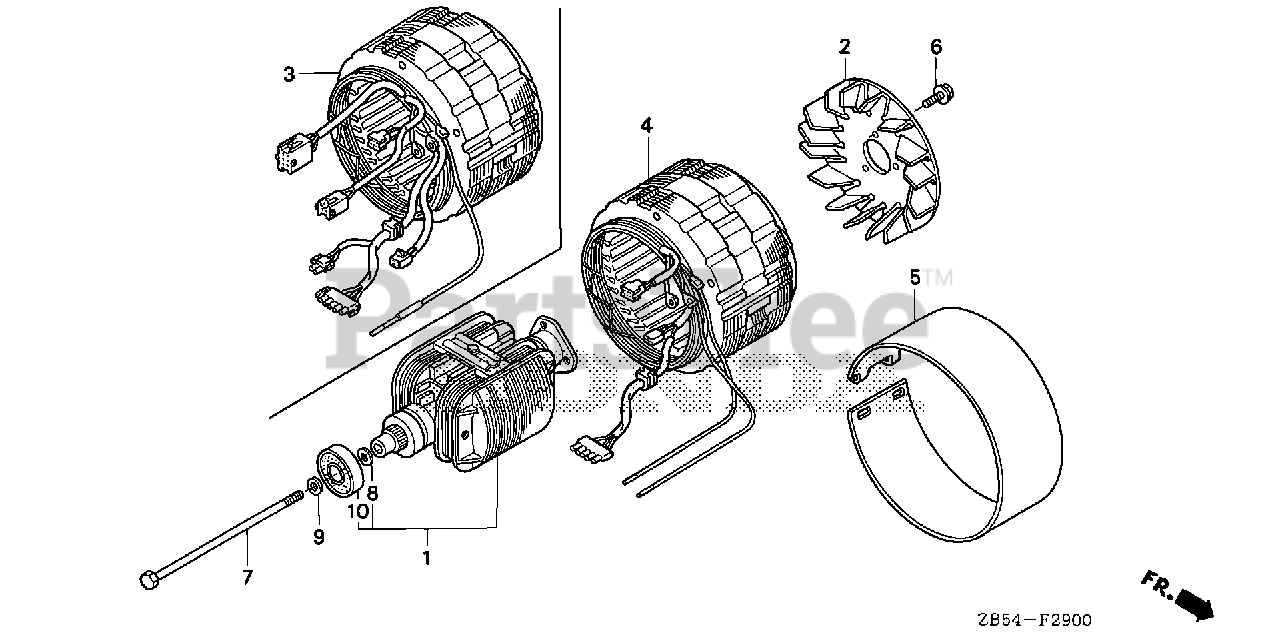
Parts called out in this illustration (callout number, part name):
1	ROTOR (003)
3	STATOR ASSY.
5	COVER, STATOR
6	SCREW, TAPPING (5X14)
7	BOLT, HEX. (10X256)
8	WASHER, THRUST
9	WASHER, PLAIN (10MM)
10	BEARING ASSY. (6205)
